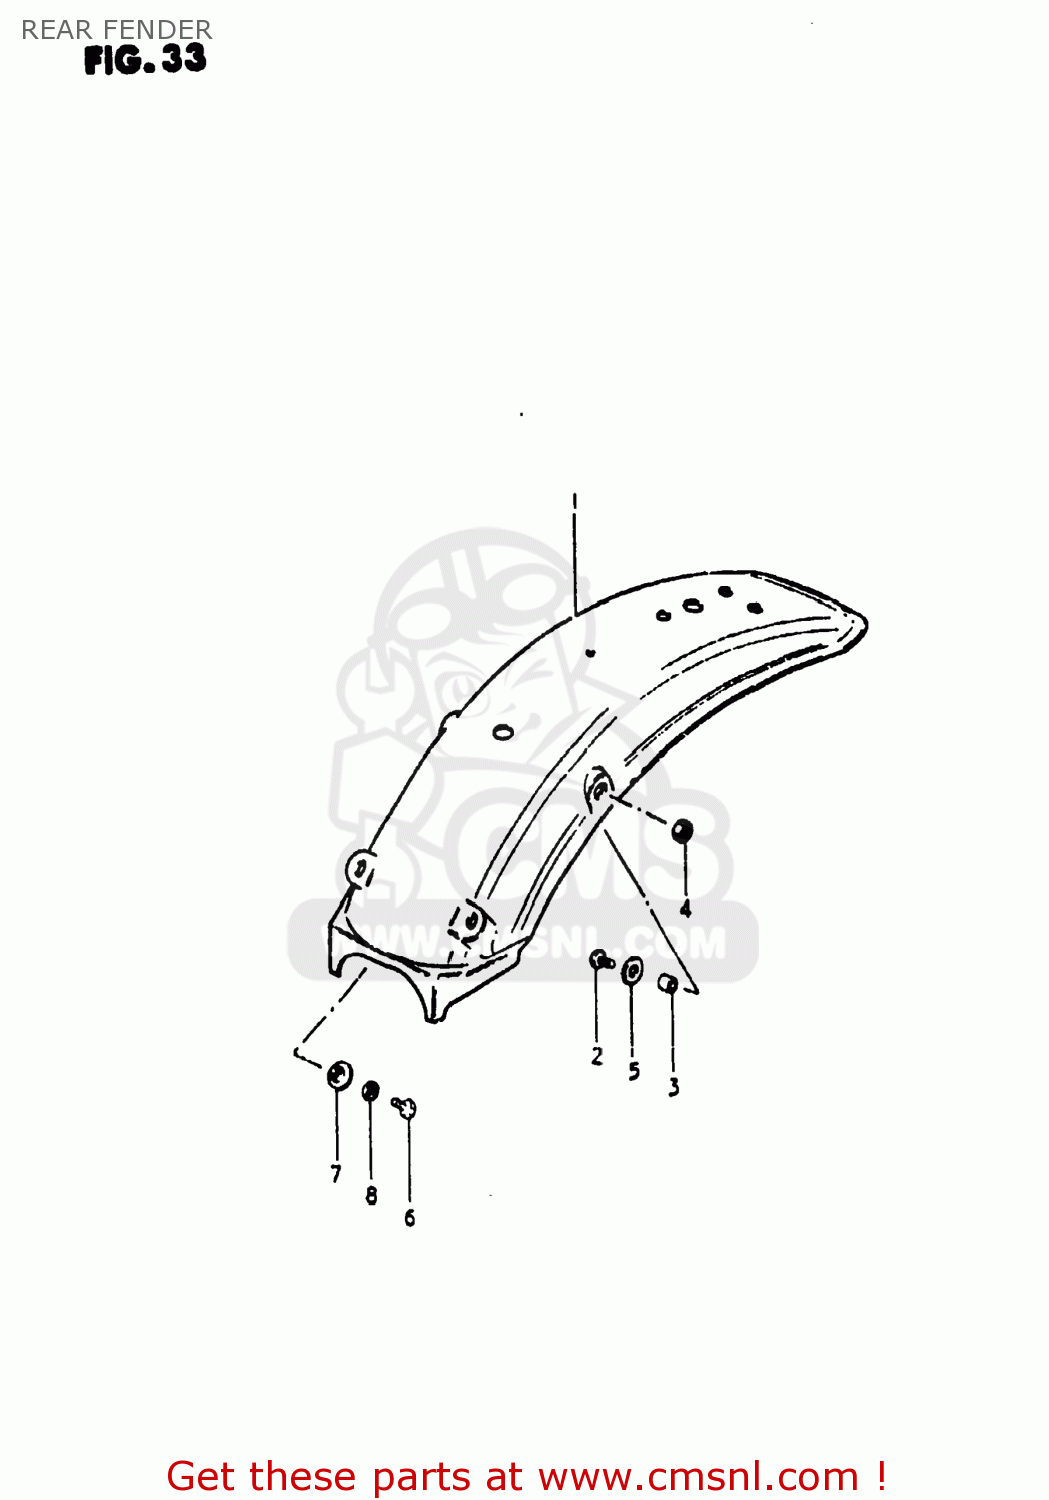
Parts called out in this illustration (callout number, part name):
1	FENDER,REAR
2	SCREW
3	SPACER
4	NUT
5	WASHER (6.5X20X1.2)
6	BOLT
7	WASHER
8	LOCK WASHER
